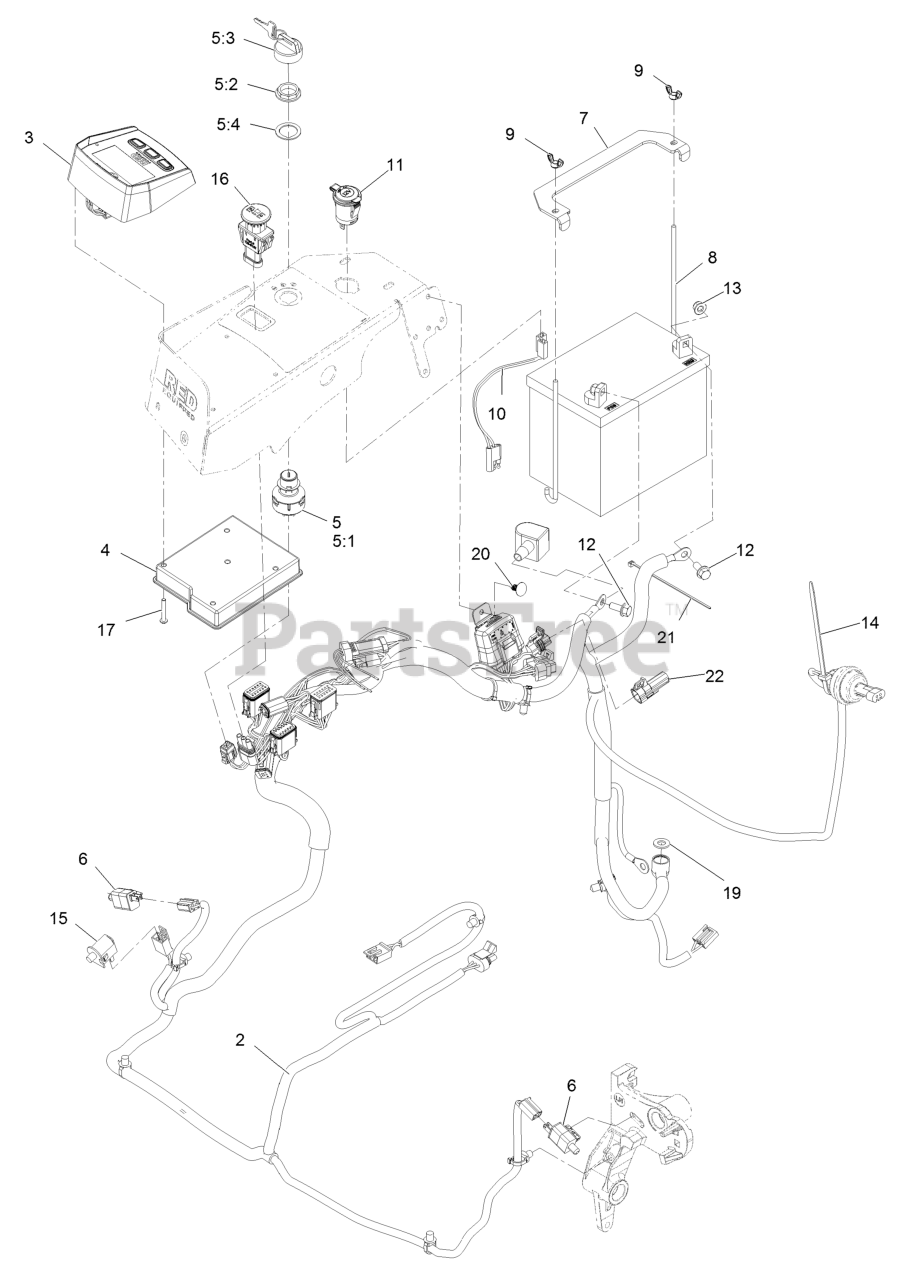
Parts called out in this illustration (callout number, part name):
2	Harness-Wire
3	Module, Ldu
4	Module-Mcu
5	Ignition Switch ASM
5:1	Switch-Ignition
5:2	Nut-Mounting
5:3	Ignition Key Set
5:4	Washer-Backup
7	Strap-Tie Down, Battery
8	Bolt-Holddown
9	Wingnut-Nyloc 1/4-20
10	Harness-Receptacle, 12V
11	Port-Power, 12V
12	Screw-HH Flg 5/16-18 X 3/
13	Nut-Nyloc 5/16-18 Flg
14	Tie-Cable 7 15/16 (Large)
16	Switch-PTO, Sealed
17	Screw-PPH
19	Washer-3/8 SAE
20	Plug-Plastic
21	Tie-Cable 5 1/2 (Small)
22	Cover-Connector, Mp150, 4M
